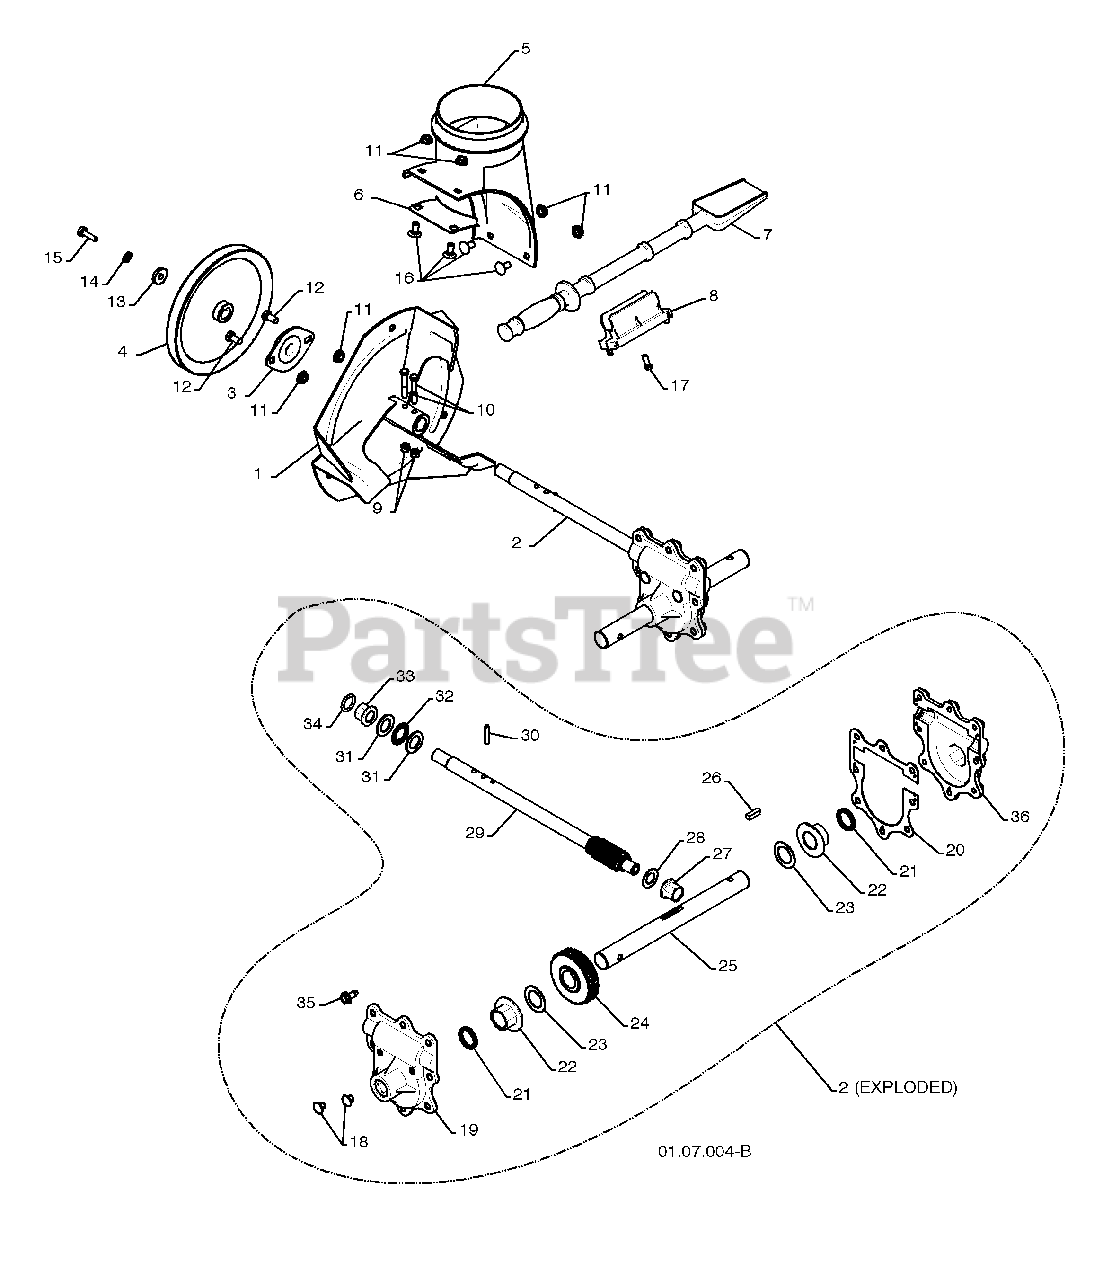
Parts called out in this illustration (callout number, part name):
1	IMPELLER
2	GEARBOX ASSEMBLY
4	IMPELLER PULLEY
5	DISCHARGE BASE
6	CORNER BRACKET
7	CLEAN OUT TOOL
9	NUT 1/4-20
10	SCREW 1/4-20 X .625
11	NUT 5/16-18
12	SCREW 5/16-18 X .625
14	LOCKWASHER 5/16
15	SCREW 5/16-18 X 1.00
16	CARRIAGE BOLT
17	SCREW 13-16 X .625
18	PLUG
19	GEARBOX COVER RH
20	GASKET
21	SEAL
22	BEARING
23	THRUST WASHER 1.00
24	WORM GEAR
25	AUGER SHAFT
26	SQUARE KEY
27	BEARING
28	THRUST WASHER
29	IMPELLER SHAFT
30	ROLL PIN
31	THRUST WASHER
32	THRUST BEARING
35	SCREW 5/16-18 X .750
36	GEARBOX COVER LH
